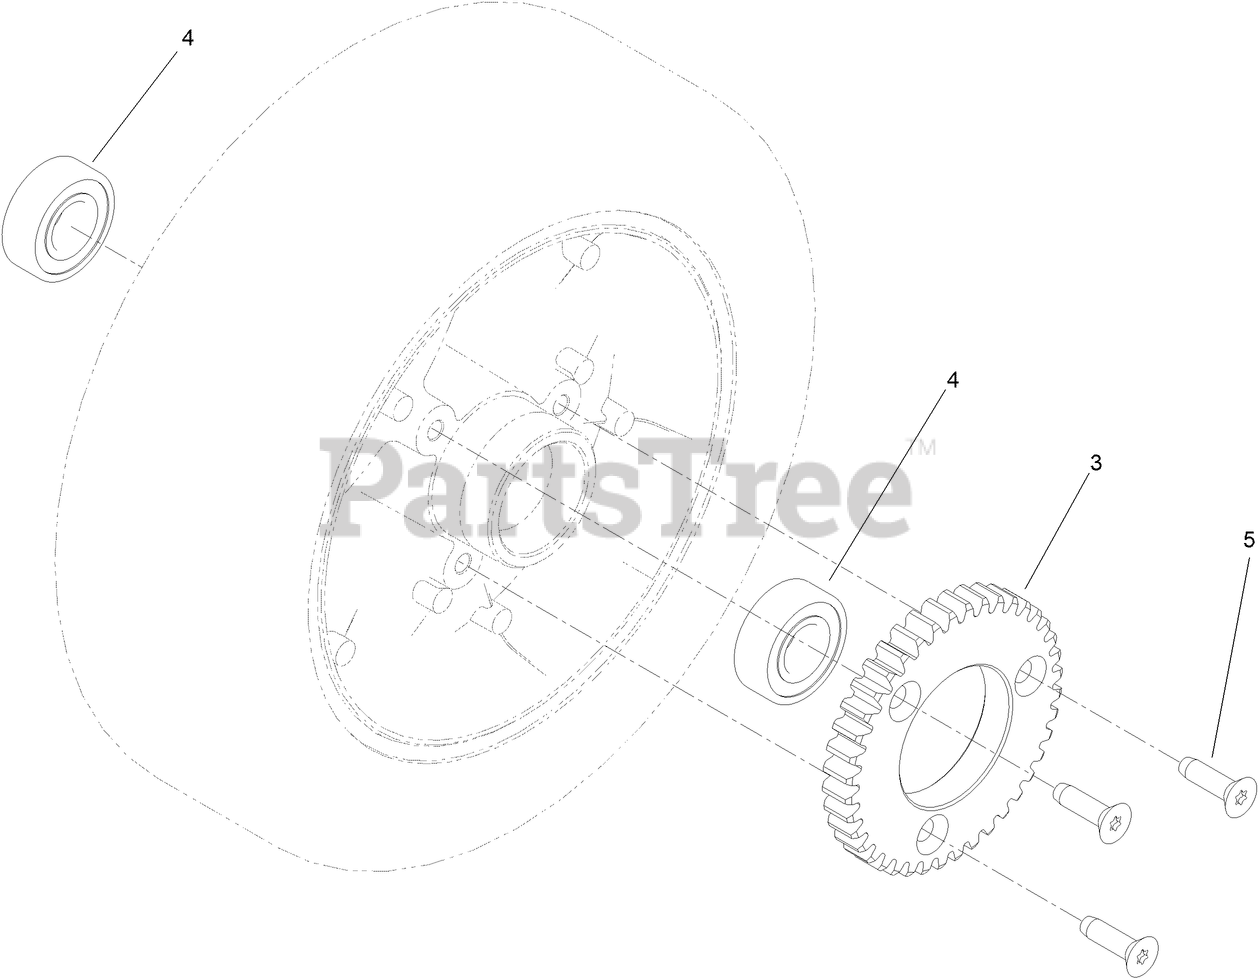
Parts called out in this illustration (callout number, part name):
3	GEAR-DRIVEN
4	BEARING-BALL
5	SCREW-TORX
